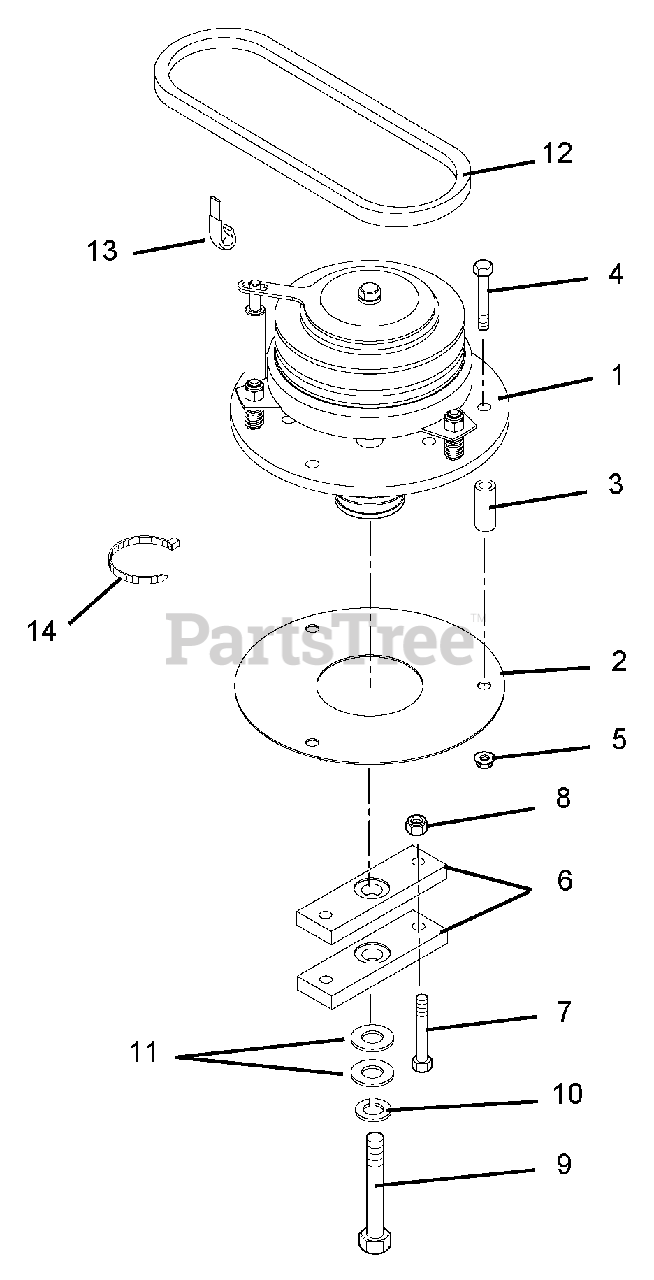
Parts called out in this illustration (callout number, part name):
1	CLUTCH & SPINDLE ASSY, RER/SZ
2	SHEILD, CLUTCH
3	SPACER .380 X .625 X 1.500
4	@BLT-HEX .38-16X2.75 GR5 YWZC
5	@NUT-LK-TOP-FLG .38-16 YWZC
6	SPACER, 28/32 BLADE
7	BLT-HEX .38-24 X 2.00 GR8 YWZC
8	NUT-LK-NYL .375-24 W/INSR YWZC
9	BLT-HEX .62-18X2.5 GR8 YZ
10	@WSHR-LK .62X.156 REG YWZC
11	@WSHR-FL-STL.656X1.31X.095 YWZ
12	BELT,HA WRAPPED
13	J-CLAMP
14	CABLE TIE LG 5-1/2
